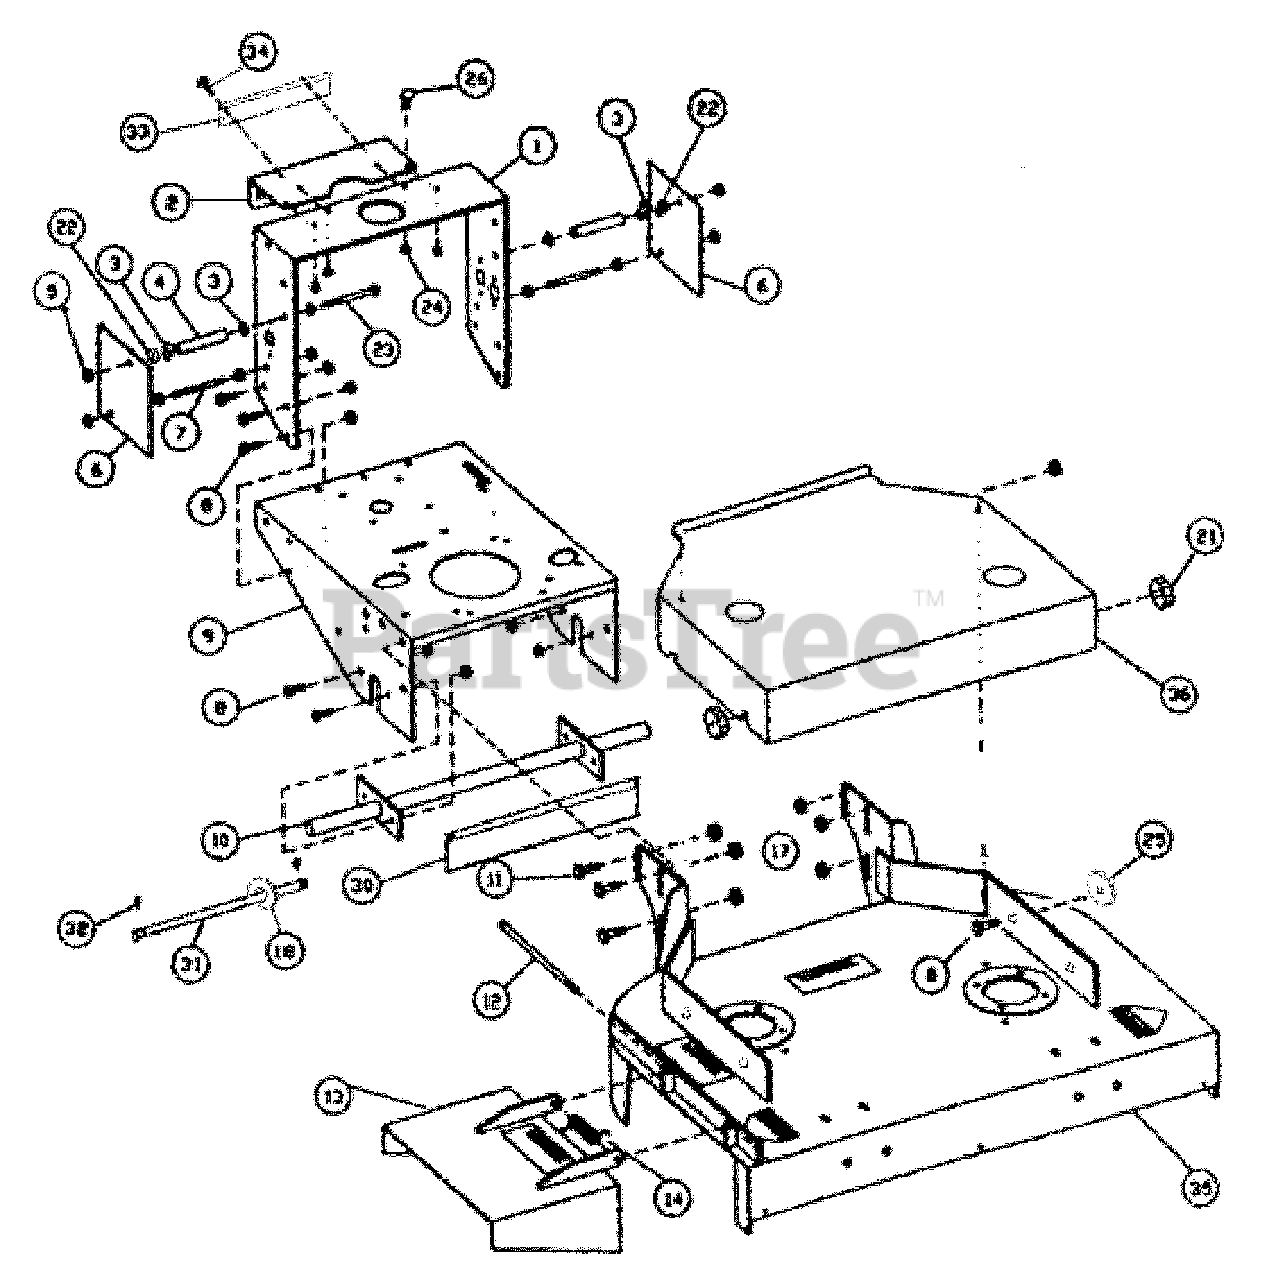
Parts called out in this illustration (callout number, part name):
2	100-002 SHIFT CONSOLE
3	100-003 WASHER
4	100-004 PIVOT TUBE
5	NUT, 200-001 M10
6	100-005 FENDER
7	BOLT, END 200-002 DBL.
8	M10X1.5X25MM HHB GR8.8
11	HHB 200-004 M12 25
12	200-005 HHB M10`240
13	100-007 CHUTE DEFLECTOR
14	100-008 TORSION SPRING
15	200-006 NYLON NUT M10
17	200-007 NYLON NUT M12
18	5/16STD FLAT WASHER.
21	100-009 SAUCER NUT
22	200-006 NYLON NUT M10
23	200-008 HEX.BOLT M10`110
24	200-009 NYLON NUT M6
25	WASHER, 3/8 STD FLAT
26	200-011 BOLT M6`16
30	100-011 SAFETY FLAP
32	200-014 COTTER PIN 2`20
33	100-116 SHIFT PLATE
34	200-063 RIVET 2`5
35	136-001BLUE DECK 36`
36	136-002BLUE HOOD 36`
